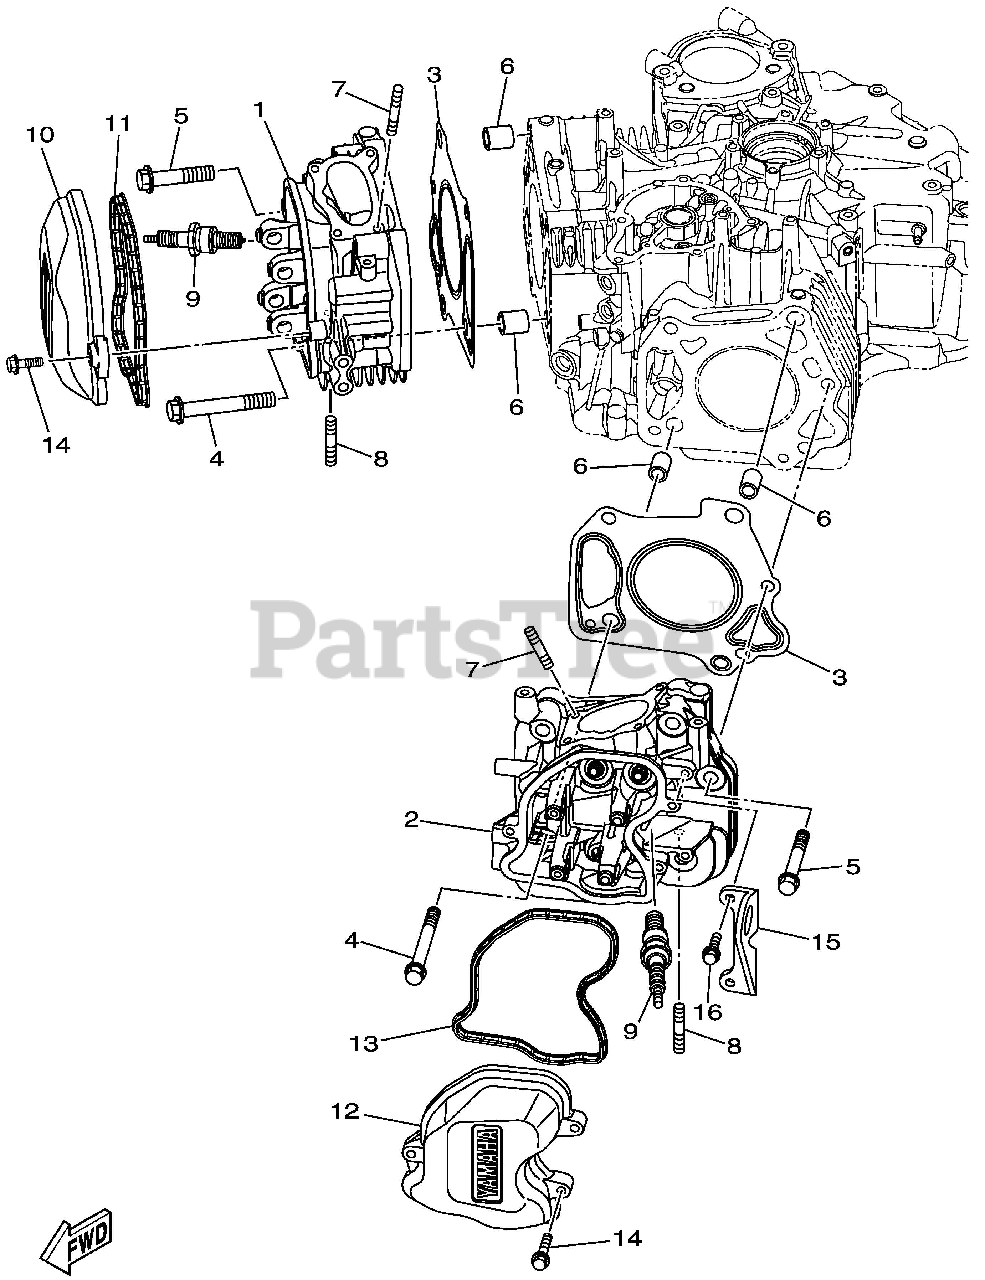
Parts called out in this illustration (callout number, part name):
1	HEAD, CYLINDER 1
2	HEAD, CYLINDER 2
3	GASKET, CYLINDER HEAD 1
4	BOLT, FLANGE
5	BOLT, FLANGE
6	PIN, DOWEL
7	BOLT, STUD
8	BOLT, STUD
9	PLUG, SPARK (NGK BPR6ES)
10	COVER, CYLINDER HEAD 1
11	SEAL, CYLINDER 1
12	COVER, CYLINDER HEAD 2
13	SEAL, CYLINDER 2
14	BOLT, FLANGE
15	HANGER, ENGINE
16	BOLT, FLANGE
